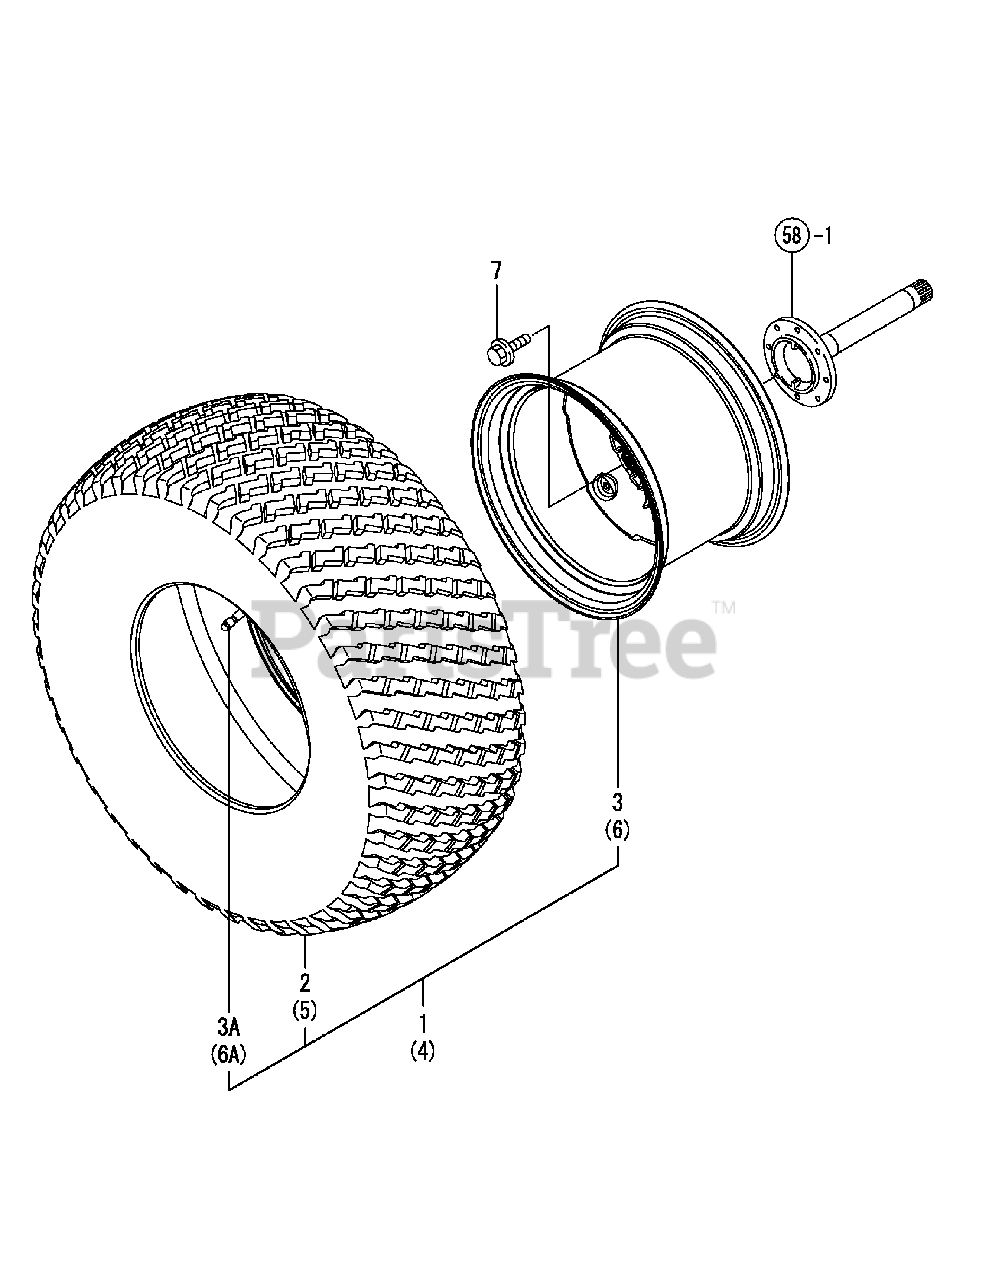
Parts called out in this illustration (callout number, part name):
1	R4 TIRE KIT,WHEEL LEFT
2	R4 TIRE 17.5L-24
4	R4 TIRE KIT,WHEEL RIGHT
5	R4 TIRE 17.5L-24
